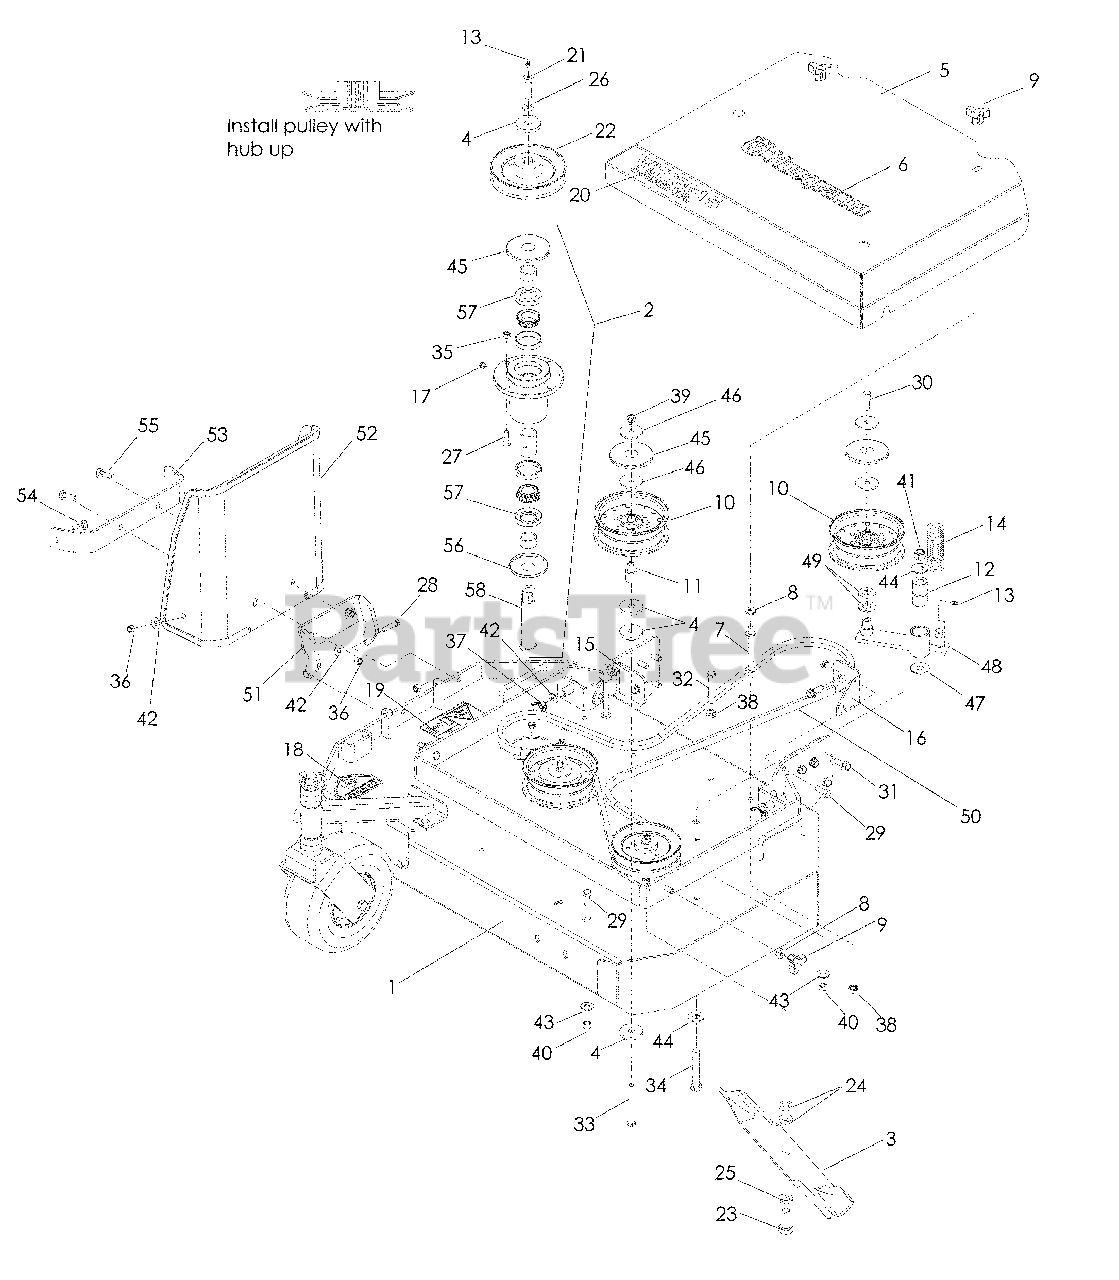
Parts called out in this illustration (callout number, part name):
1	DECK W/DECALS
2	SPINDLE ASSEM
3	BLADE, 18"
4	HEAVY WASHER
5	BELT SHIELD, 36"
6	DECAL, HUSQ
7	SHIELD SPACER
8	WASHER 3/8" SEALING
9	KNOB THREE PRONG
10	PULLEY IDLER
11	BUSHING IDLER
12	BUSHING PIVOT
13	ZERK
15	DECK SLIDE, RT
16	DECK SLIDE, LT
17	GREASE POPPET
18	DECAL, CPSC
19	DECAL, SEVERING
20	DECAL, WH3615
21	HCS 7/16-20 x 1½ GR8 SPEC
23	HCS 5/8-18 x 1½ TPBLT
24	BLADE SPACER
25	WASHER 5/8 SLW
26	WASHER 7/16 SLW
27	HCS 5/16-18 x 1
28	HCS 5/16-18 x 1¼
29	HCS 3/8-16 x 1
30	HCS 3/8-16 x 1¼
31	HCS 3/8-16 x 1 WHIZLK
32	HCS 3/8-16 x 2½
33	HCS 3/8-16 x 3½
34	HCS ½-13 x 3¼
35	NUT 5/16-18 HEX CTRLK
36	NUT 5/16-18 HEX NYLOC
37	NUT 5/16-18 WING NYLON
38	NUT 3/8-16 HEX WHIZLK
39	NUT, 3/8-16 HEX CNTRLK
40	NUT 3/8-16 HEX NYLOC
41	NUT ½ HEX NYLOC
42	WASHER, 5/16 STD FLT
43	WASHER, 3/8 FLAT STD
44	WASHER, ½ STD FLT
45	TOP DUST CAP
46	WASHER - 3/8 SPECIAL
47	WASHER, ½
48	IDLER ARM- ANGLED
49	WASHER, 5/8 SAE FLT
50	BELT, DECK
51	PIVOT BRACKET, DECK
52	CHUTE, RUBBER
53	BRACKET, CHUTE
54	RHSNB 5/16-18 x 1¼
55	RHSNB 5/16-18 x 1½
56	BOTTOM DUST CAP
57	SHAFT SEAL
